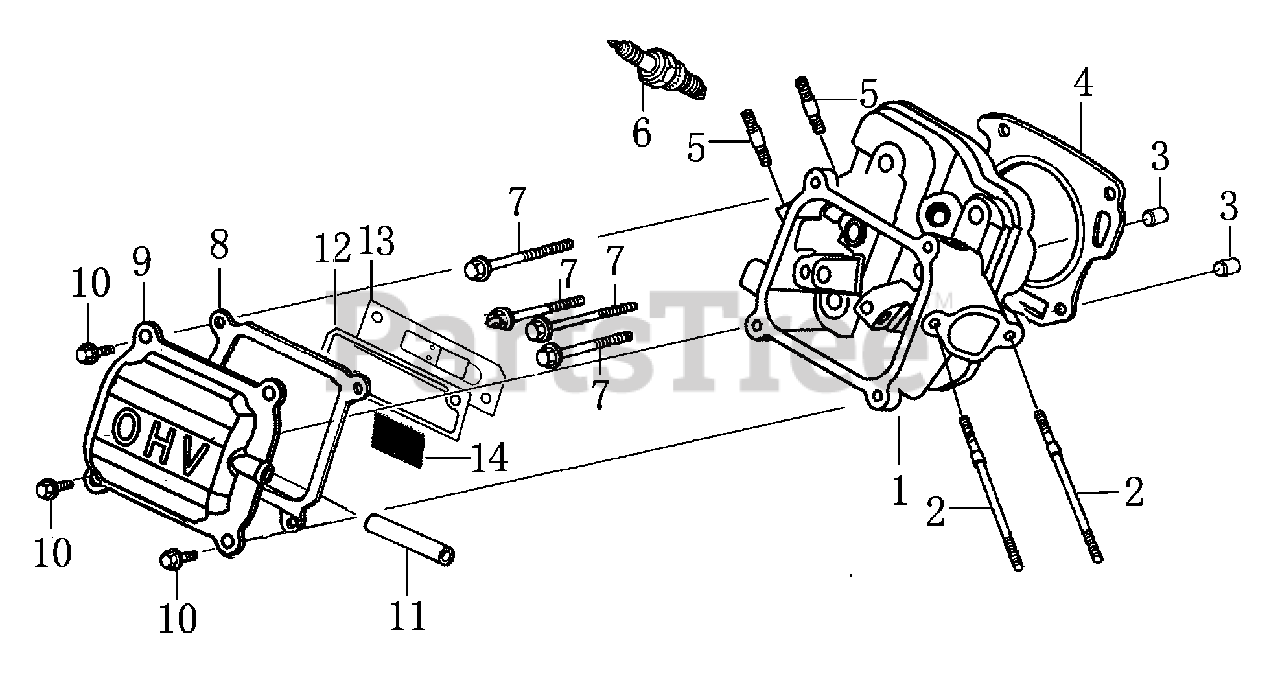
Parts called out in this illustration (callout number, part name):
1	CYLINDER HEAD
2	INTAKE STUDS
3	DOWEL PIN
4	CYLINDER HEAD GASKET
5	EXHAUST STUDS
6	SPARK PLUG
7	FLANGE HEAD BOLT (M8X60)
8	HEAD COVER GASKET
9	HEAD COVER
10	FLANGE BOLT (M8*60)
11	BREATHER TUBE
12	BREATHER CHANBER GASKET
13	BREATHER CHAMBER CAP
14	OIL STRAINER
